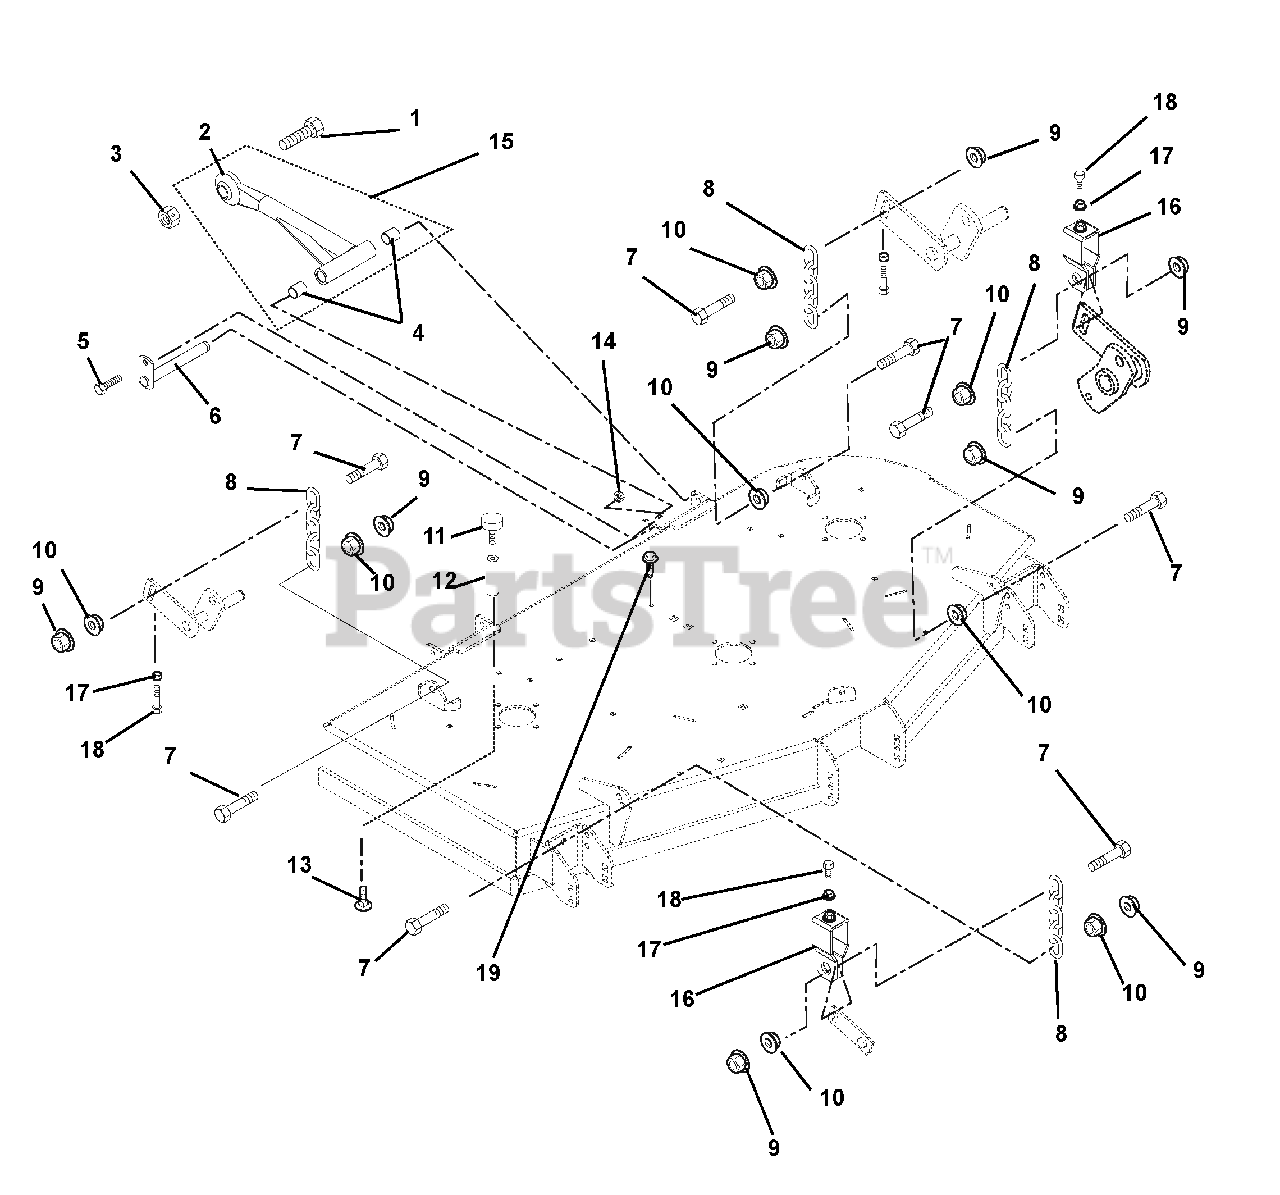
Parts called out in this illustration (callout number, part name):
1	BLT-HEX .875-9X2.75 GR5 YWZC
2	MOWER MOUNTING ARM WMT - BLACK
3	NUT-LK-CTR .875-9 YWZC
4	BRG, .750 X .875 X 1.000
5	@BLT-HEX .38-16X1.00 GR5 YWZC
6	WELDMENT, MOWER MTG. PIN
7	BLT, HEX M12-1.75X50 CLS8.8 YZ
8	CHAIN, LINK
9	NUT-SPNLK-FLG M12-1.75 YZ
10	NUT-SPNLK-FLG M12-1.75 YZ
11	BUMPER, RUBBER
12	NUT, COUPLING .31-18 X 3.00
13	BLT,RDHDSQNK .31-18X.75 LOCTIT
14	@NUT-LK-NYL-FLG .38-16 YWZC
15	ASSM, MOWER MOUNTING ARM
16	BRKT, DECK LEVELING
17	NUT- JAM .312-18 YWZC
18	BLT-HEX .312-18X2.00 FTH GR5YZ
19	@SCR-TAP .38-16X.50 HWH TR YWZ
